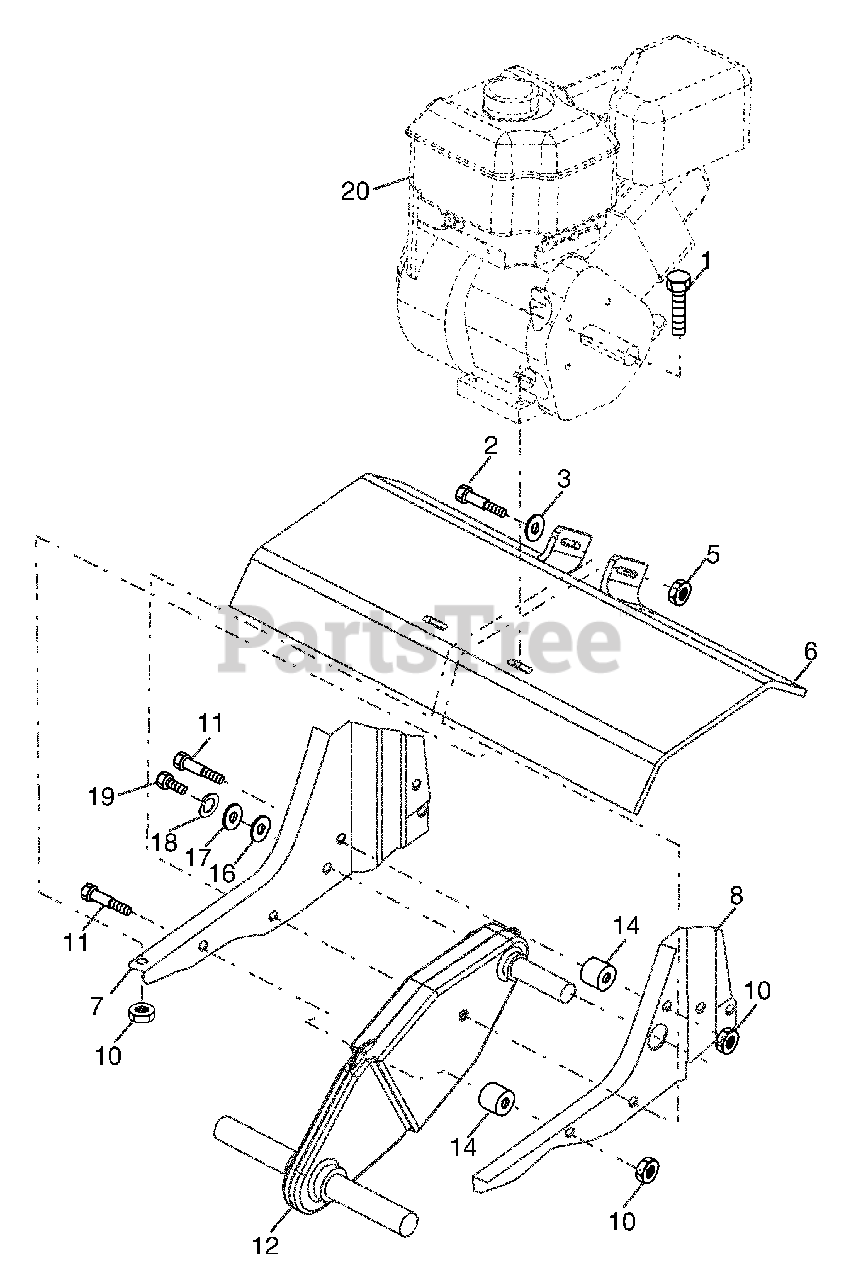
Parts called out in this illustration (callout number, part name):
1	Bolt, Hex 5/16-18 x 1-1/2 Gr. 2
2	Bolt, Hex, Fin 3/8-16 x 3-1/4
3	Washer 13/32 x 13/16 x 11
5	Nut Lock Flg 3/8-16 unc
6	Shield, Tine
7	Bracket, Engine, R.H.
8	Bracket, Engine, L.H.
10	Nut Lock Hex Flg
11	Bolt, Shoulder
12	Transmission
14	Spacer, Split
16	Washer 9/32 x 7/8 x 12 Ga.
17	Washer 9/32 x 1-1/4 x 16 Ga.
18	Washer, Lock 1/4
19	Bolt, Hex 1/4-28 x 3/4 Gr. 5
